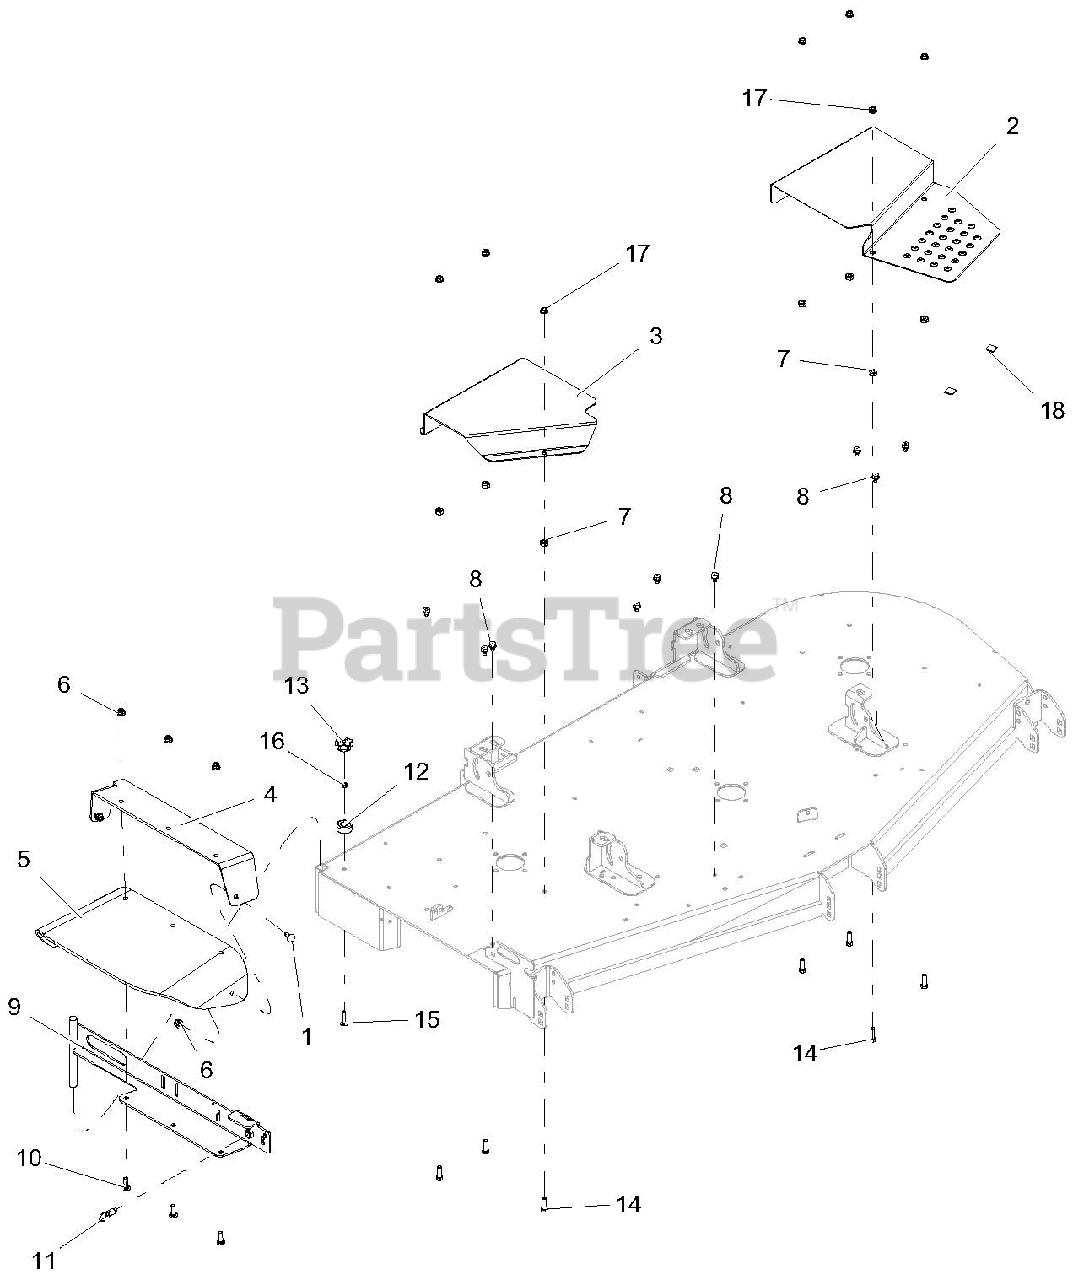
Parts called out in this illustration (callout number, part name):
1	BLT-RDHDSQNK .38-16X1.00 G5 YWZC
2	GUARD, 72" LH DECK BELT-RED
3	GUARD, 72" RH DECK BELT-RED
4	SUPPORT, CHUTE MOUNTING BRACKET-RED
5	CHUTE, RUBBER DISCHARGE
6	NUT-LK-NYL-FLG .38-16 YWZC
7	NUT-HEAVY HEX .38-16 YWZC
8	SCR-TAP .38-16X.50 HWH TR YWZ
9	WLDMT, 66"-72" DISCH CHUTE MTG-RED
10	BLT-RDHDSQNK .38-16X1.25 G5 YWZC
11	PULL PIN,.50-13THDX.310 PLNGR
12	BUMPER, RECESSED 1.50 X .63 W/.31 HOLE
13	KNOB, CLAMPING
14	BLT-HEX .38-16X1.25 GR5 YWZC
15	BLT-RDHDSQNK .31-18X1.50 G5 YWZC
16	NUT-LK-CTR .31-18 YWZC
17	@NUT-SPNLK-FLG .375-16 YWZC
